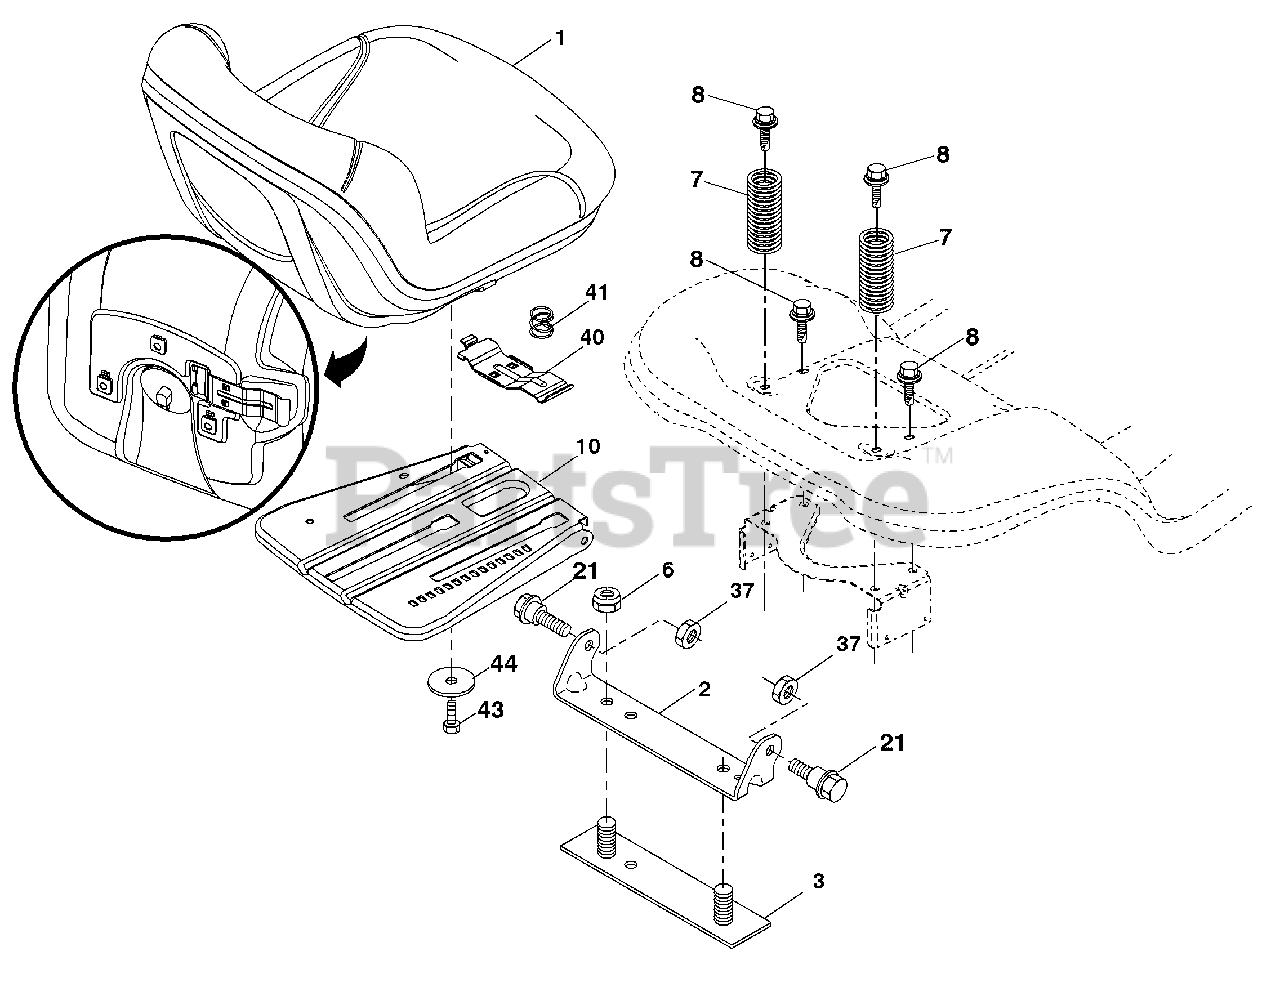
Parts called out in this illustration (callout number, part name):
1	Seat
2	Bracket Pivot Fender
3	Strap, Asm Fender
5	Clip, Push In, Hinged
6	Nut, Lock W/Ins. 3/8-16 unc
7	Spring, Seat Cprsn
8	Bolt 5/16-18 uncx 3/4 w/Sems
10	Pan, Seat
21	Bolt, Shoulder 5/16-18
37	Nut, Lock 5/16-18 unc
40	Handle Slide Seat
41	Spring Latch Seat
43	Bolt Fin Hex 3/8-16 unc x 3/4
44	Washer 13/32 x 2-3/8 x 12 Ga.
